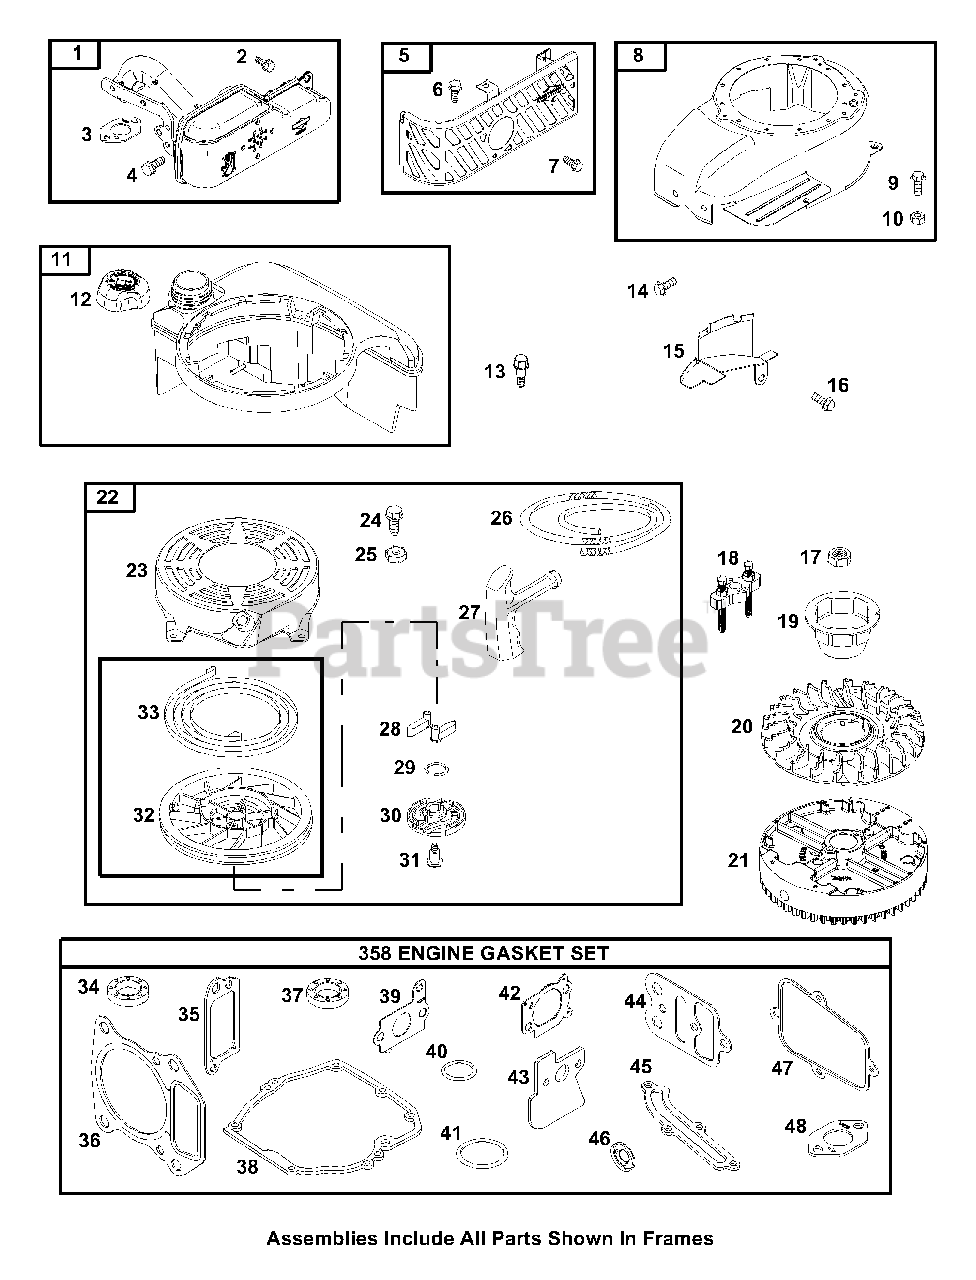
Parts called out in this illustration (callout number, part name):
1	Muffler
2	Screw (Muffler)
3	Gasket (Exhaust)
4	Screw (Muffler)
5	Guard-Muffler
6	Screw (Muffler Guard)
7	Screw (Muffler Guard)
8	Housing-Blower
9	Screw (Blower Housing)
10	Nut (Blower Housing)
11	Tank Fuel
12	Cap-Fuel Tank
13	Screw (Fuel Tank)
14	Screw (Blower Housing)
15	Guard-Flywheel
16	Screw (Flywheel Guard)
17	Nut (Flywheel)
18	Puller-Flywheel
19	Cup-Flywheel
20	Fan-Flywheel
22	Starter-Rewind
23	Housing-Rewind Starter
24	Screw (Rewind Starter)
25	Nut (Rewind Starter)
26	Rope-Starter
27	Grip-Starter Rope
28	Ratchet-Pawl
29	Spring-Friction
30	Plate-Pawl Friction
31	Screw (Pawl Friction Plate)
32	Pulley/Spring Assembly (Pulley)
33	Pulley/Spring Assembly (Spring)
34	Seal-Oil (Magneto Side)
35	Gasket-Breather
36	Gasket-Cylinder Hd.
37	Seal-Oil (PTO Side)
38	Gasket-Crankcase
39	Gasket-Intake
40	Seal-Dipstick Tube
41	O-Ring Seal (Dipstick/tube seal)
42	Gasket-Air Cleaner
43	Spacer-Carburetor
44	Gasket-Cylinder Head Plate
45	Gasket-Breather Passage
46	Seal-Valve
47	Gasket (Rocker Cover)
48	Gasket-Exhaust
358	Engine Gasket Set
